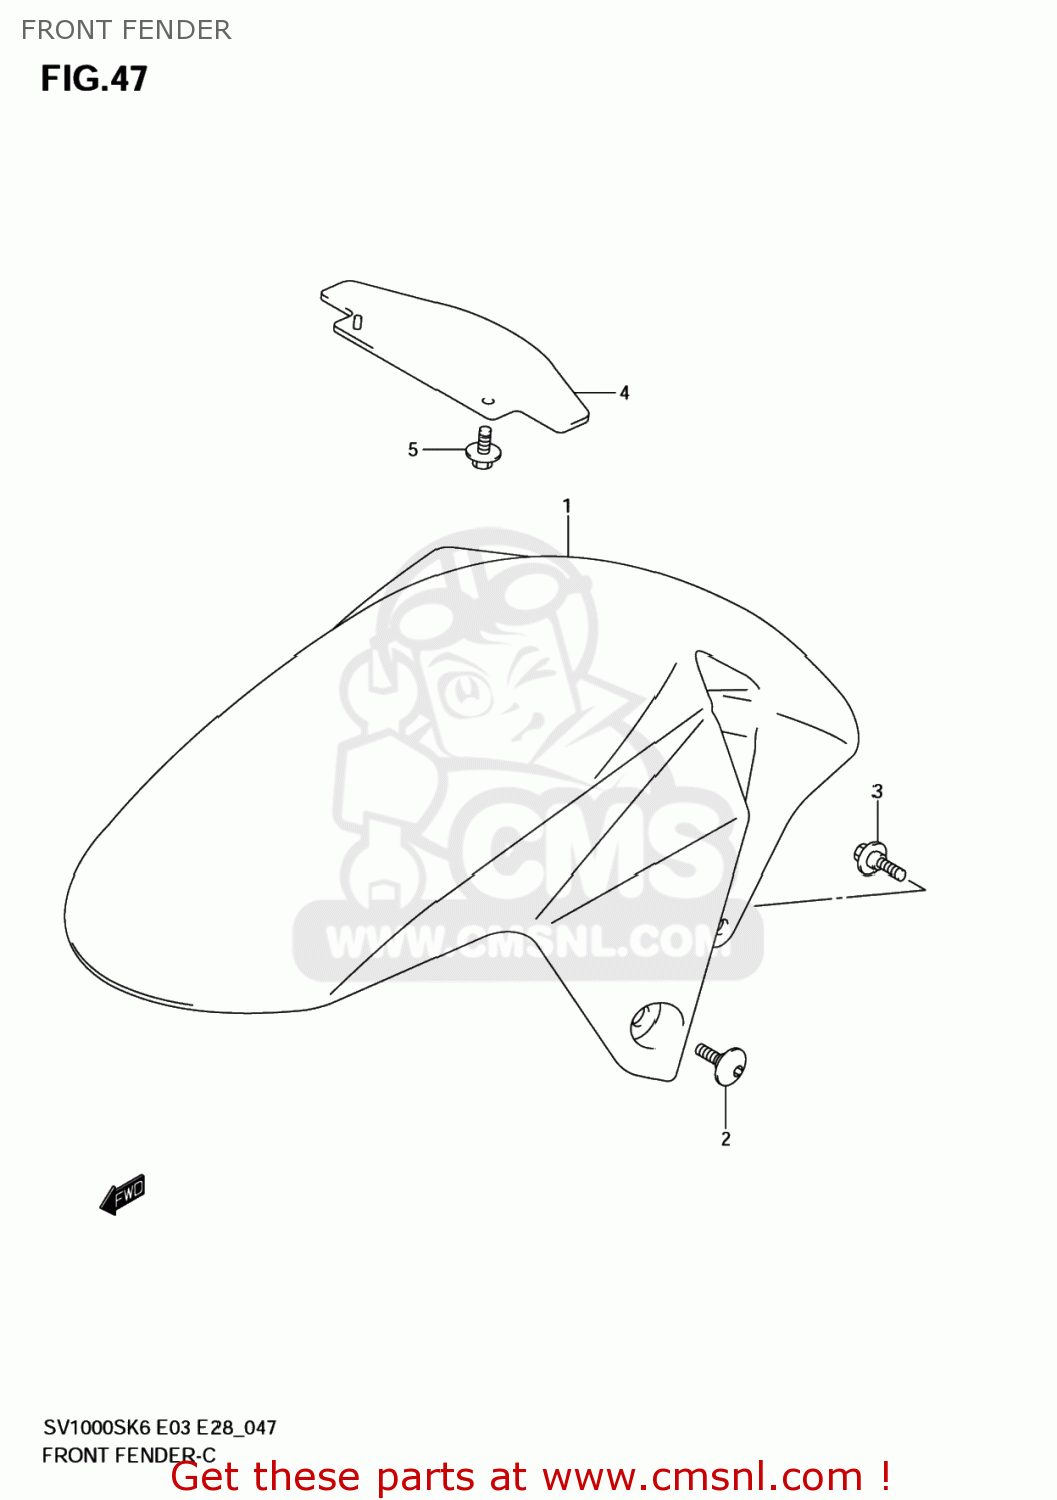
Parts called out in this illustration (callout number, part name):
1	FENDER,FRONT
2	SCREW(6X16)
3	SCREW(6X16)
4	FENDER,FR UPPER
5	BOLT(6X12)
